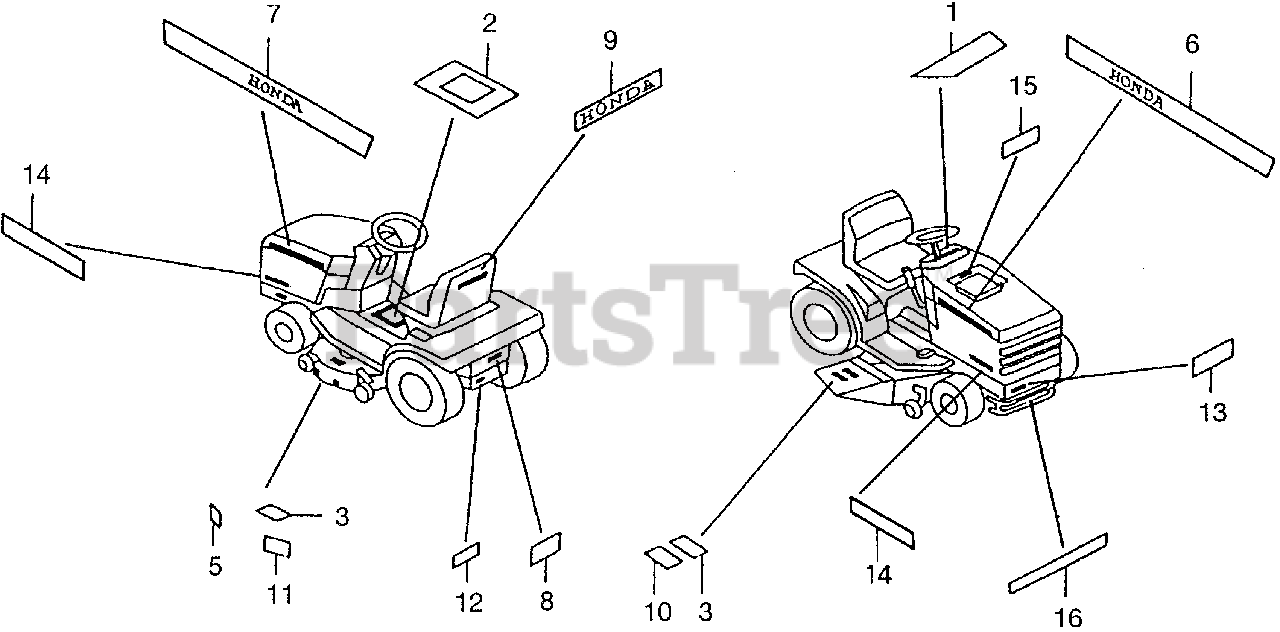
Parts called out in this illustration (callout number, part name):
1	LABEL, DASH
2	LABEL, OPERATION
3	LABEL, WARNING (A)
5	MARK, INCH SIZE (38)
6	MARK, R. STRIPE
7	MARK, L. STRIPE
8	LABEL, MANUAL
9	MARK, SEAT EMBLEM
10	MARK KIT
10	MARK, DANGER (A)
11	MARK, HEIGHT OPERATION
12	MARK, MANUFACTURER
13	MARK KIT
13	LABEL, HEAT WARNING
14	MARK, SALES POINT
15	LABEL, SCREEN
16	MARK, FIRE CAUTION
